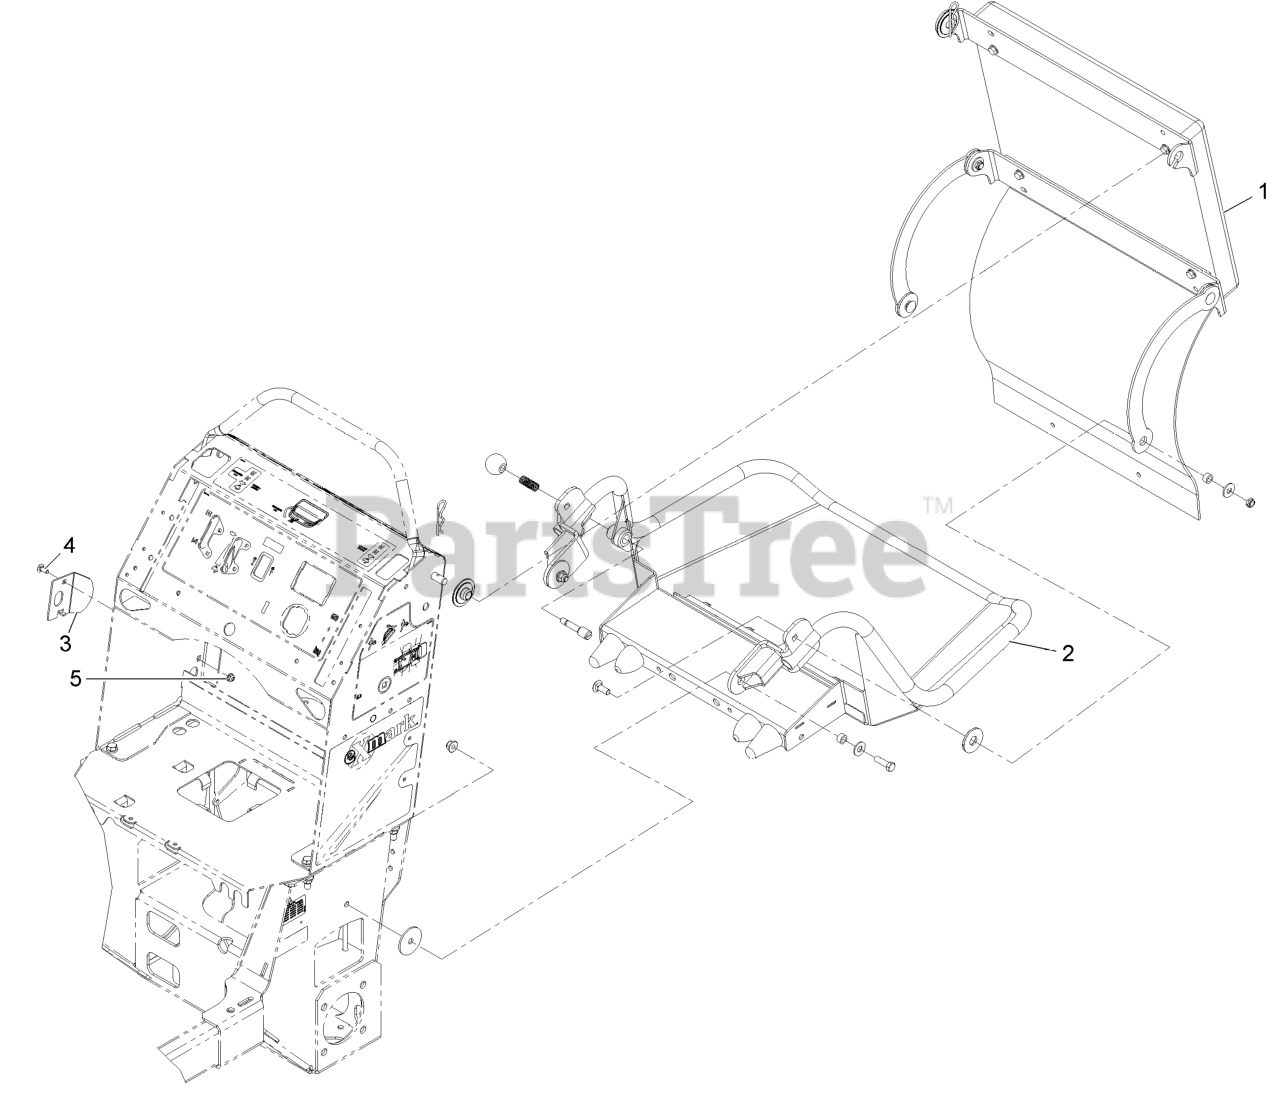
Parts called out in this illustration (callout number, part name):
2	PLATFORM ASM
3	PLATE-STRIKER
4	SCREW-CARR
